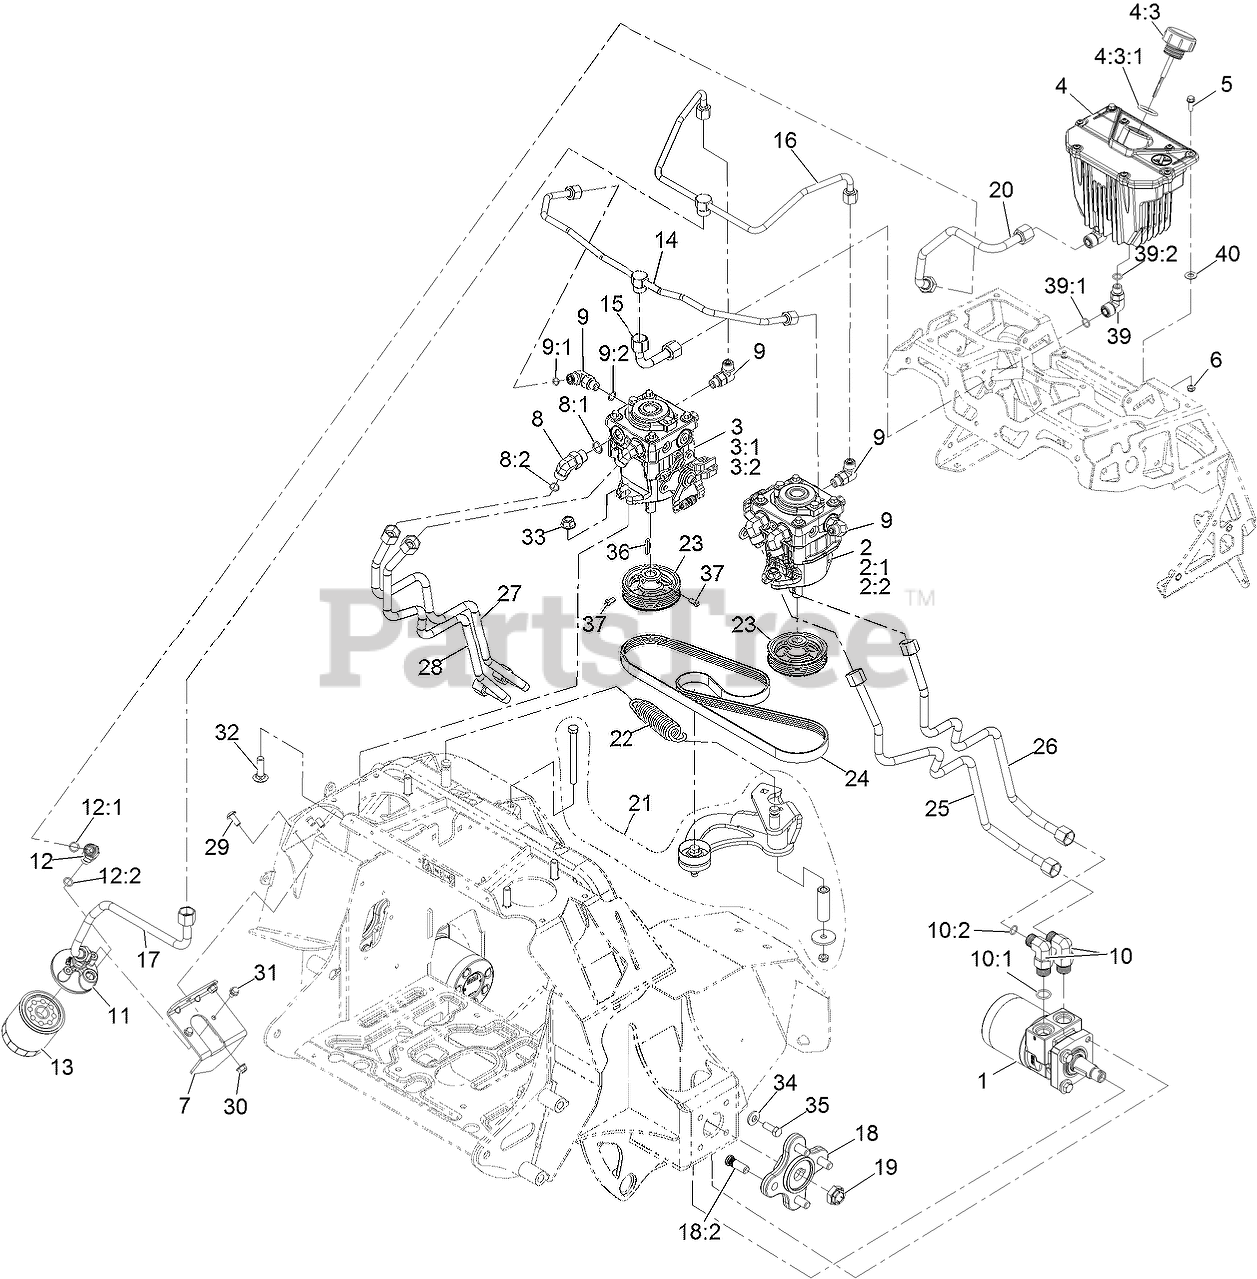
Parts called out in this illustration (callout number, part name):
1	Motor-Wheel
2	PUMP-HYDRAULIC 10CC
2:1	KIT, 10CC PUMP KIT
2:2	SEAL OVERHAUL KIT
3	PUMP-HYDRAULIC 10CC
3:1	KIT, 10CC PUMP KIT
3:2	SEAL OVERHAUL KIT
4	ASM, Hydraulic Reservoir
4:3	Cap, Hydraulic
5	SCREW-HWH
6	NUT-LOCK, NI
7	Bracket-Filter
8	FITTING-ELBOW, 90 DEG
8:1	O-RING
8:2	O-RING
9	FITTING-ELBOW, 90 DEG
9:1	O-RING
9:2	O-RING
10	FITTING-ELBOW, 90 DEG
10:1	O-RING
10:2	O-RING
11	HEAD-FILTER
12	Adapter
12:1	O-RING
12:2	O-RING
13	FILTER-25 MICRON, BI-DIRE
14	Line, Hydraulic, Case Tee
15	Line, Hydraulic, Case
16	Line, Hydraulic, Charge Tee
17	Line-Hydraulic Charge
18	ASM-Hub And Studs
18:2	STUD-WHEEL
19	NUT-LOCK
20	Line-Hydraulic Supply
21	ASM, Idler Arm
22	SPRING, EXTENSION
23	PULLEY, PUMP
24	Belt, Pvk5
25	Kit-Ste HYD Line B-A
26	Kit-Ste HYD Line A-B
27	Kit-Ste HYD Line B-B
28	Kit-Ste HYD Line A-A
29	SCREW-TORX
30	NUT-HF, NI
31	SCREW-HHF
32	BOLT-CARR
33	NUT-HF, NI
34	WASHER-BELLEVILLE
35	SCREW-HH
36	Key, 5Mm X 5Mm X 29Mm
37	Screw-SQH
39	Fitting-HYD, 90 DEG
39:1	O-RING
39:2	O-RING
40	Washer-Thrust
